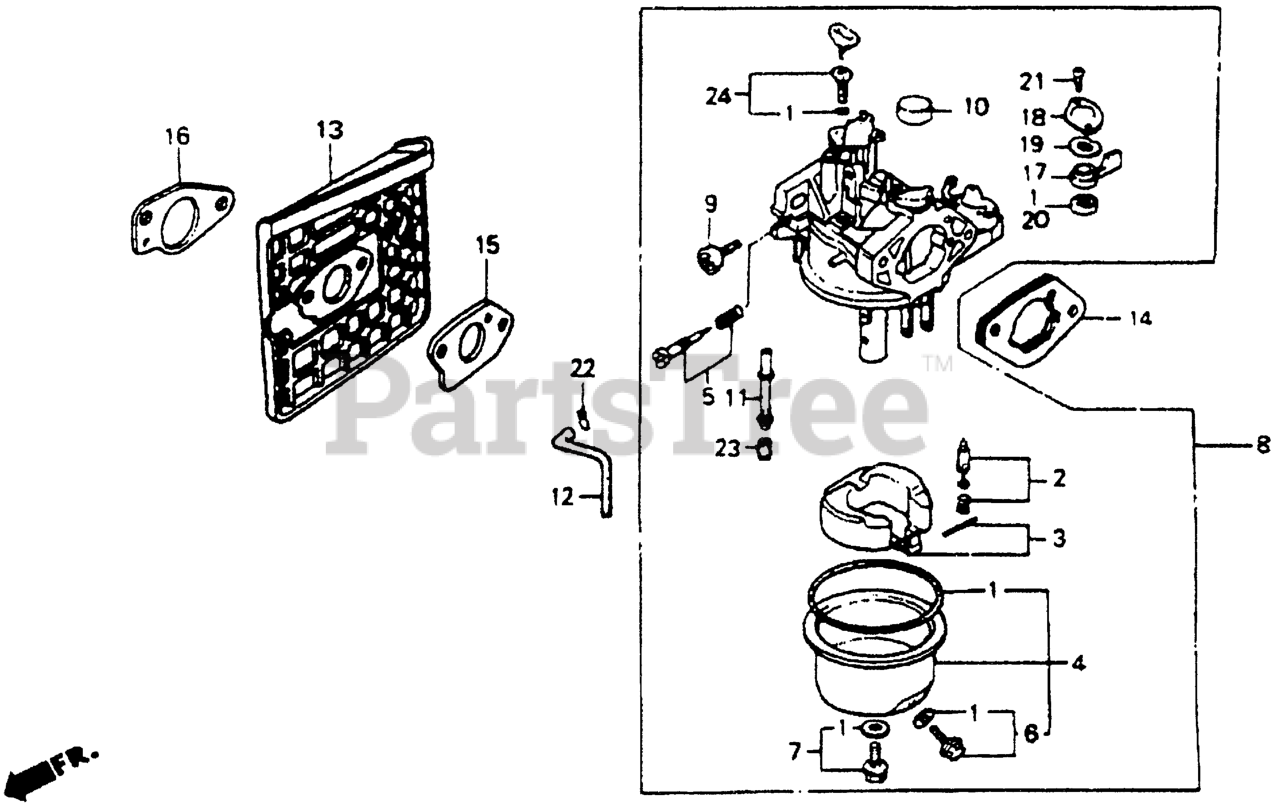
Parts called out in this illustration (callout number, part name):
1	GASKET SET (EXC. 16173-001-004) (CARBURETOR NO.) (EXCEPT 16173-001-004)
2	VALVE SET, FLOAT
3	FLOAT SET
4	CHAMBER SET, FLOAT
5	SCREW SET, PILOT (CARBURETOR NO.)
6	SCREW SET, DRAIN (Honda Code 1672187). (CARBURETOR NO.)
7	SCREW SET
8	CARBURETOR ASSY. (BE32A C)
9	SCREW, THROTTLE STOP
10	CAP, CHOKE LEVER DUST
11	NOZZLE, MAIN
12	TUBE, AIR VENT (75MM)
13	INSULATOR, CARBURETOR
14	SPACER, CARBURETOR
15	GASKET, CARBURETOR
16	GASKET, INSULATOR
17	LEVER, VALVE
18	PLATE, LEVER SETTING (CARBURETOR NO.)
19	SPRING, PETCOCK LEVER (CARBURETOR NO.)
20	GASKET, VALVE
21	SCREW, PAN (3X6)
21	SCREW, PAN (3X8) (CARBURETOR NO.)
22	CLIP, TUBE (B8)
23	JET, MAIN (#92) Use up to Engine SN BE37B A.
23	JET, MAIN (#95) Use up to Engine SN BE37B A.
23	JET, MAIN (#90) Use from Engine SN BE81B C.
24	JET SET, PILOT (#40)
